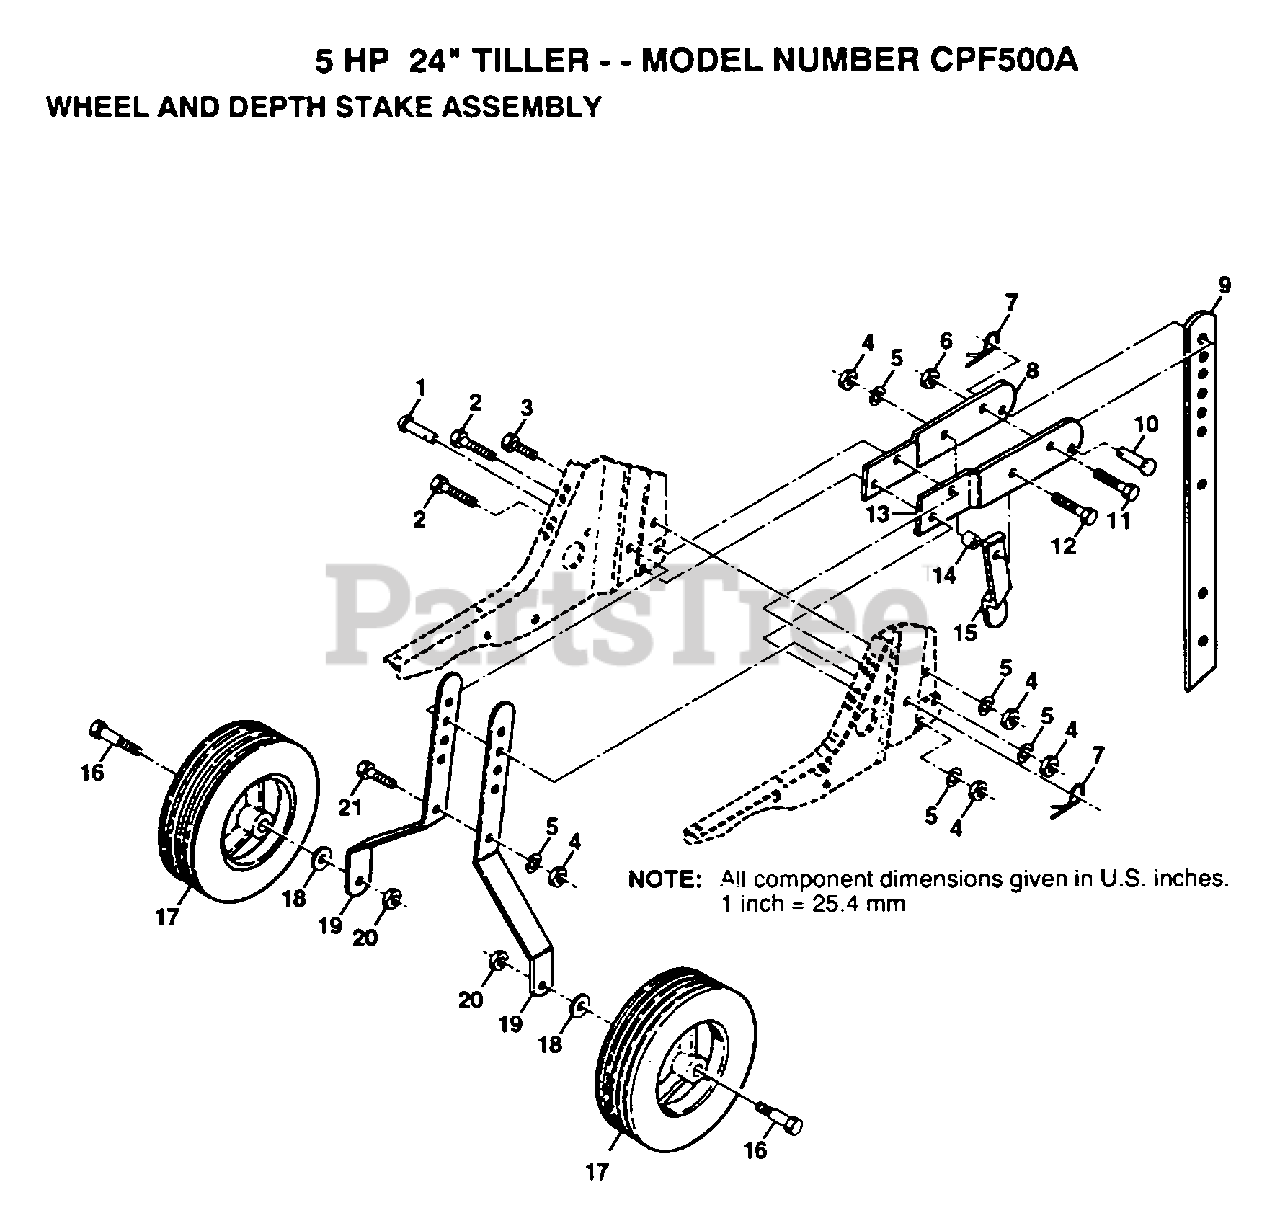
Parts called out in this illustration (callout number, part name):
1	DRILLED RIVET RT
3	BOLT
4	NUT.HEX.5/16-18
5	LOCKWASHER
6	GRIPCO NUT
7	SPRING.RETAINER
11	BOLT.3/8-24X1-1/2
12	BOLT.HEX.5/16-1.5
14	WASHER
15	STAKE SPRING TI
16	BOLT SHOULDER
18	WASHER
